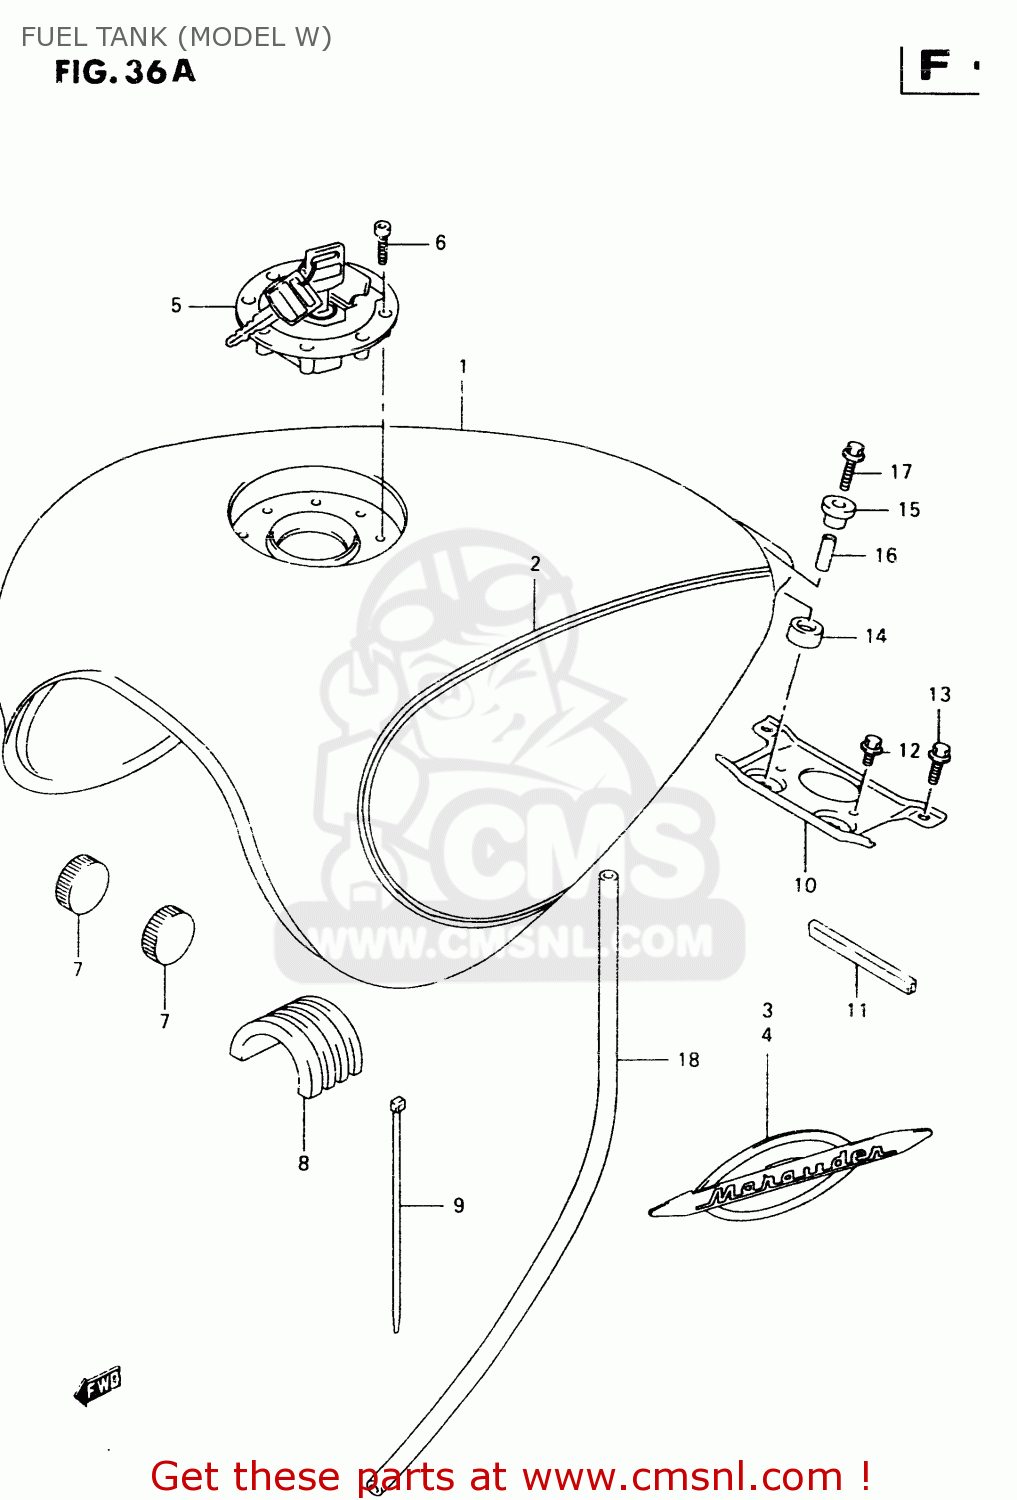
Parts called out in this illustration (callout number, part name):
1	TANK ASSY,FUEL
2	TAPE SET,FUEL TANK
3	EMBLEM,FUEL TANK,R
4	EMBLEM,FUEL TANK,L
5	CAP SET,FUEL TANK
6	BOLT(5X20)
7	CUSHION
8	CUSHION,FUEL TANK UPR
9	CLAMP(L:250)
10	BRACKET,FUEL TANK RR
11	PROTECTOR
12	BOLT
13	BOLT
14	CUSHION,FUEL TANK RR NO.2
15	CUSHION
16	SPACER(6.5X10.5X22.5)
17	BOLT
18	HOSE,DRAIN
